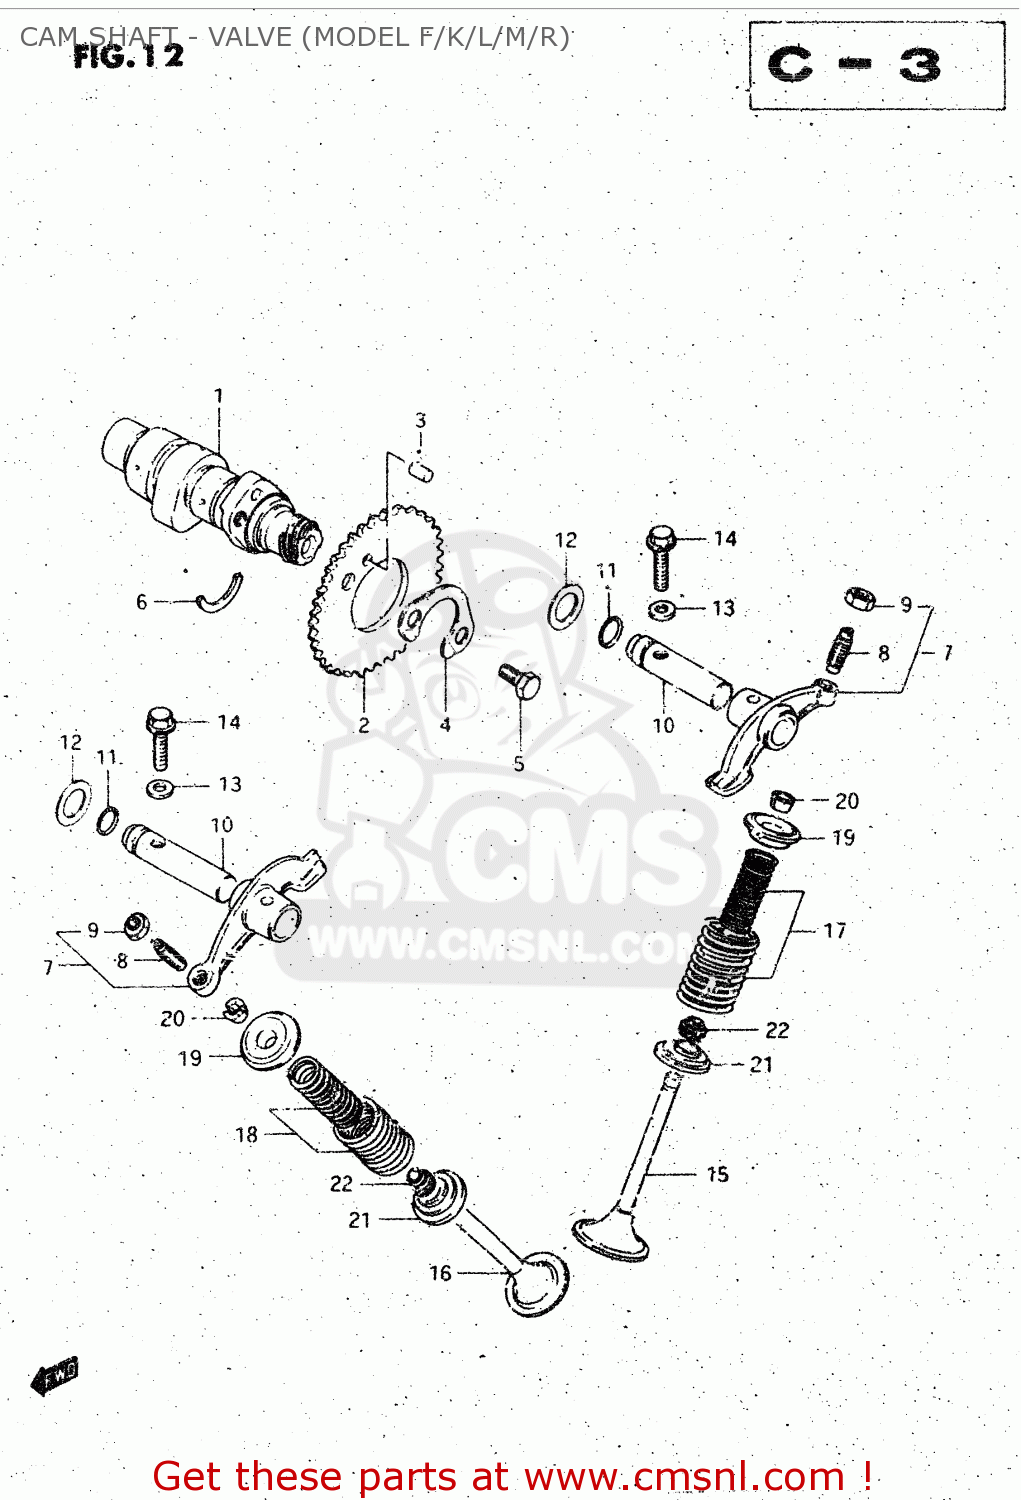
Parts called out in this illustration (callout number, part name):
1	CAMSHAFT
2	SPROCKET,CAMSHAFT
3	PIN(5X8)
4	WASHER,SPROCKET
5	BOLT(6X10.5)
6	C RING
7	ARM,VALVE ROCKER
8	SCREW,TAPPET ADJUSTING
9	NUT,ADJUSTING SCREW
10	SHAFT,VALVE ROCKET
11	O RING(D:1.9,ID:8.6)
12	WASHER
13	GASKET(5.8X13X1.2) (NAS)
14	BOLT
15	VALVE,INTAKE
16	VALVE,EXHAUST
17	SPRING SET,VALVE
18	SPRING SET,VALVE
19	RETAINER,VALVE SPRING
20	COTTER,VALVE
21	SEAT,VALVE SPRING
22	SEAL,OIL(5.5X11X8.2)
